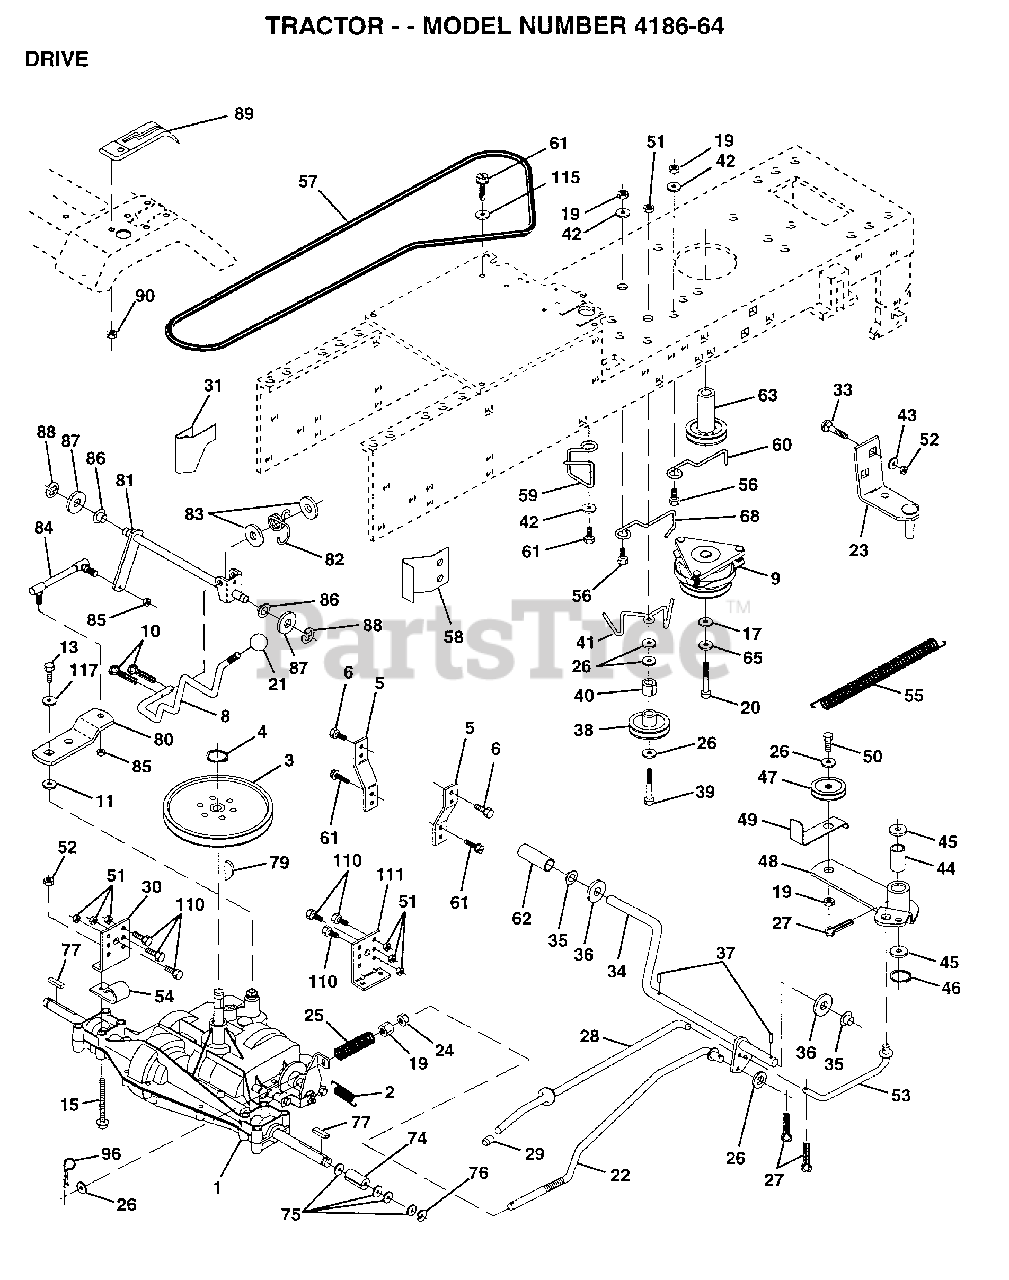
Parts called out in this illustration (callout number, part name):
1	TRANSAX. PRLES.
3	PULLEY TRANSAXLE
4	RING
5	STRAP TORQUE
6	SCREW
8	ROD SHIFT FEND YT
10	PIN COTTER 1/8
11	WASH-SHFT PLT LT
13	BOLT.1/4-28.W/PAT
15	BOLT.HX.FLG.5/16
17	WASHER
19	NUT
20	BOLT.7/16-20X4.25
21	KNOB T (1/2-HOLE)
22	ROD.ASM.BK.44.MWR
23	BRACKET.ASM.MTG
24	NUT
25	"SPRING,ROD BRAKE"
26	WASHER
27	COTTER PIN
28	ROD.BRAKE.PARK.LT
29	PLUNGER CAP T
30	BRKT TRANS LH
31	KEEPER BELT LH
33	BOLT
34	SHAFT FOOT PEDAL
35	NYLON BEARING
36	WASHER LT
38	PULLEY.IDLER.FLAT
39	BOLT
40	SPACER T
41	KEEPER BELT
42	WASHER
43	WASHER T
44	"LY, BEARING"
45	WASHER LT
46	KLIP RING
48	ARM IDLER
49	RETAIN BELT
53	"LINK, CLUTCH T"
54	"CLIP,INSULATOR"
55	"SPRING, RETURN LT"
57	BELT.GRDRV.94.75
58	"KEEPER,BELT RH"
59	KEEPER BELT CNTSP
60	KEEPER BELT ENGLH
61	SCREW
62	PEDAL COVER T
63	PULLEY ENGINE
65	LOCKWASHER
68	"KEEPER,BLT ENG LT"
74	SPACER HYT
75	WASHER
76	E RING HYT
77	SQ KEY STD
80	"ARM,SHIFT"
81	"SHAFT,SHIFTER"
82	"SPRING,TORSION"
83	WASHER
84	"ROD,TIE "
85	NUT.CNT.LOCK.1/4
86	BUSHING
87	WASHER D
88	KLIP RING
89	CONSOLE SHIFTER
90	NUT
96	RETAINER M
111	BRKT TRANS RH
115	WASHER GT
117	WASHER PM
